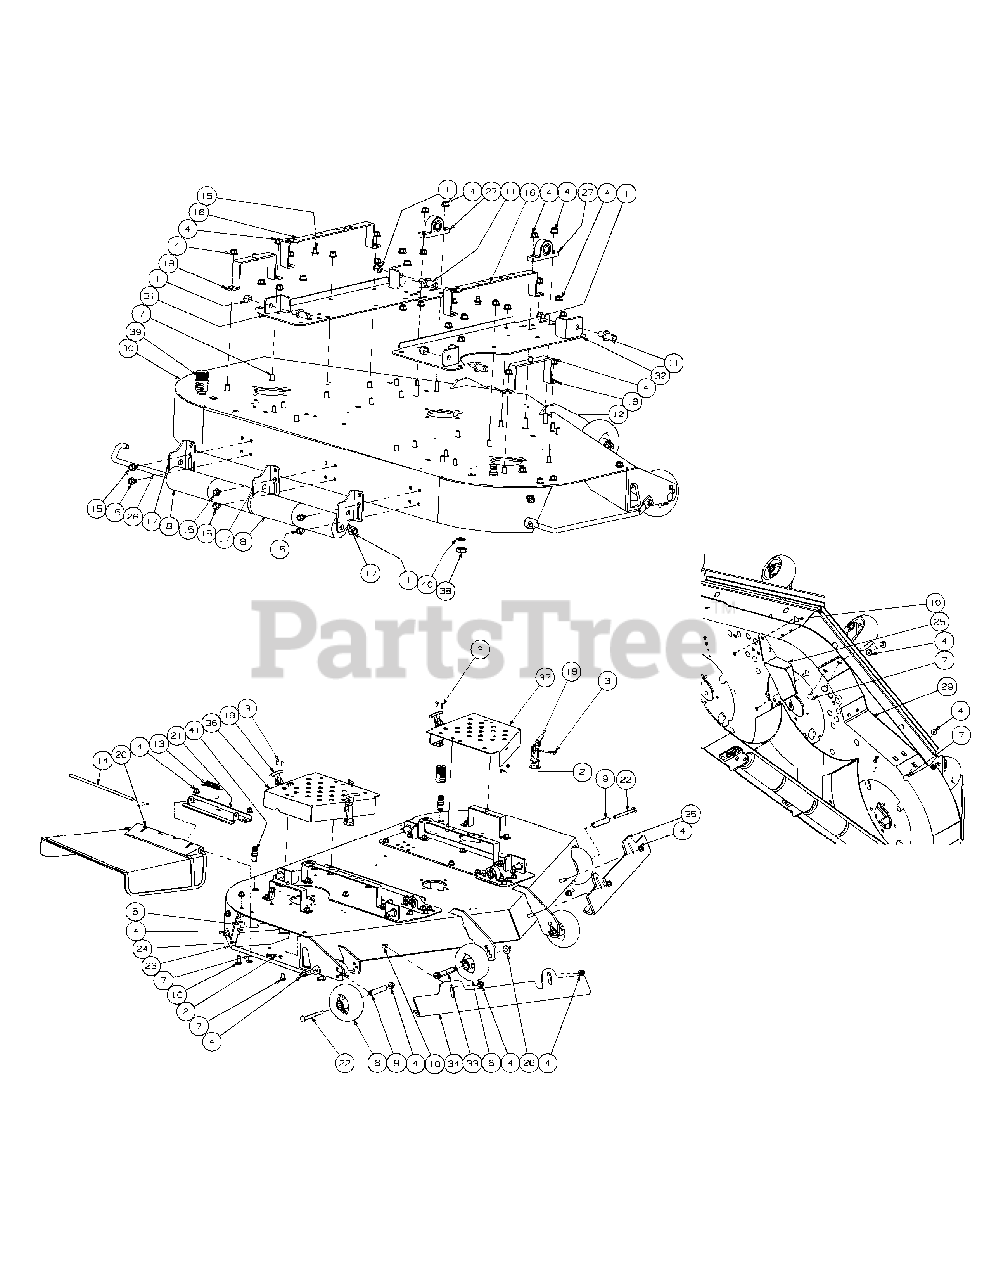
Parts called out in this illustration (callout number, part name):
1	Lock Nut, Nylon Insert, 1/2-13
2	Lock Nut, Nylon Insert, 10-32
3	Phillips Head Screw, 10-32
4	Hex Nut, 3/8-16 Flange Lock
5	Idler Washer
6	Complete Wheel, 5.00 Dia.
7	Carriage Bolt, 3/8-16 x .75 Lg.
8	Front Roller
9	Wheel Spacer
10	Carriage Bolt, 3/8-16 x 1
11	Pin, 5/8 Dia. x 1.2 Lg.
12	Carriage Screw, 3/8-16 x 1.25
13	Spring Torsion, 0.4 ID x 2.16 LG
14	Defllector Chute Rod
15	Hex Index Washer Screw, 3/8-16, .5
16	Cover Support
18	Outer Belt Cover Support Assembly
19	T-Handle Draw Latch
20	Deflector Chute
21	Deflector Chute Bracket
22	Carriage Bolt, 3/8-16 x 4.00
23	Finger Guard
25	Discharge Baffle Weldment
26	Nut, 1/2-13, Flangelock
27	Pillow Block
28	J-Hook w/ Threaded Roller
29	Baffle, 54" Adjustment
30	54" Deck Assembly
31	Left Hand Deck Weldment Mounting Plate
32	Right Hand Deck Weldment Mounting Plate
33	Shoulder Bolt, .625 x 3.00 x 3/8-16
34	Right Hand Front Adjustment Skirt
35	Left Hand Front Adjustment Skirt
36	Right Hand Belt Cover
37	Left Hand Belt Cover
38	Hex Nut, M16-1.5
39	Water Nozzle Adaptor
40	Lock Washer, 17 x 23.8 x 1.95
41	Deck Water Nozzle
